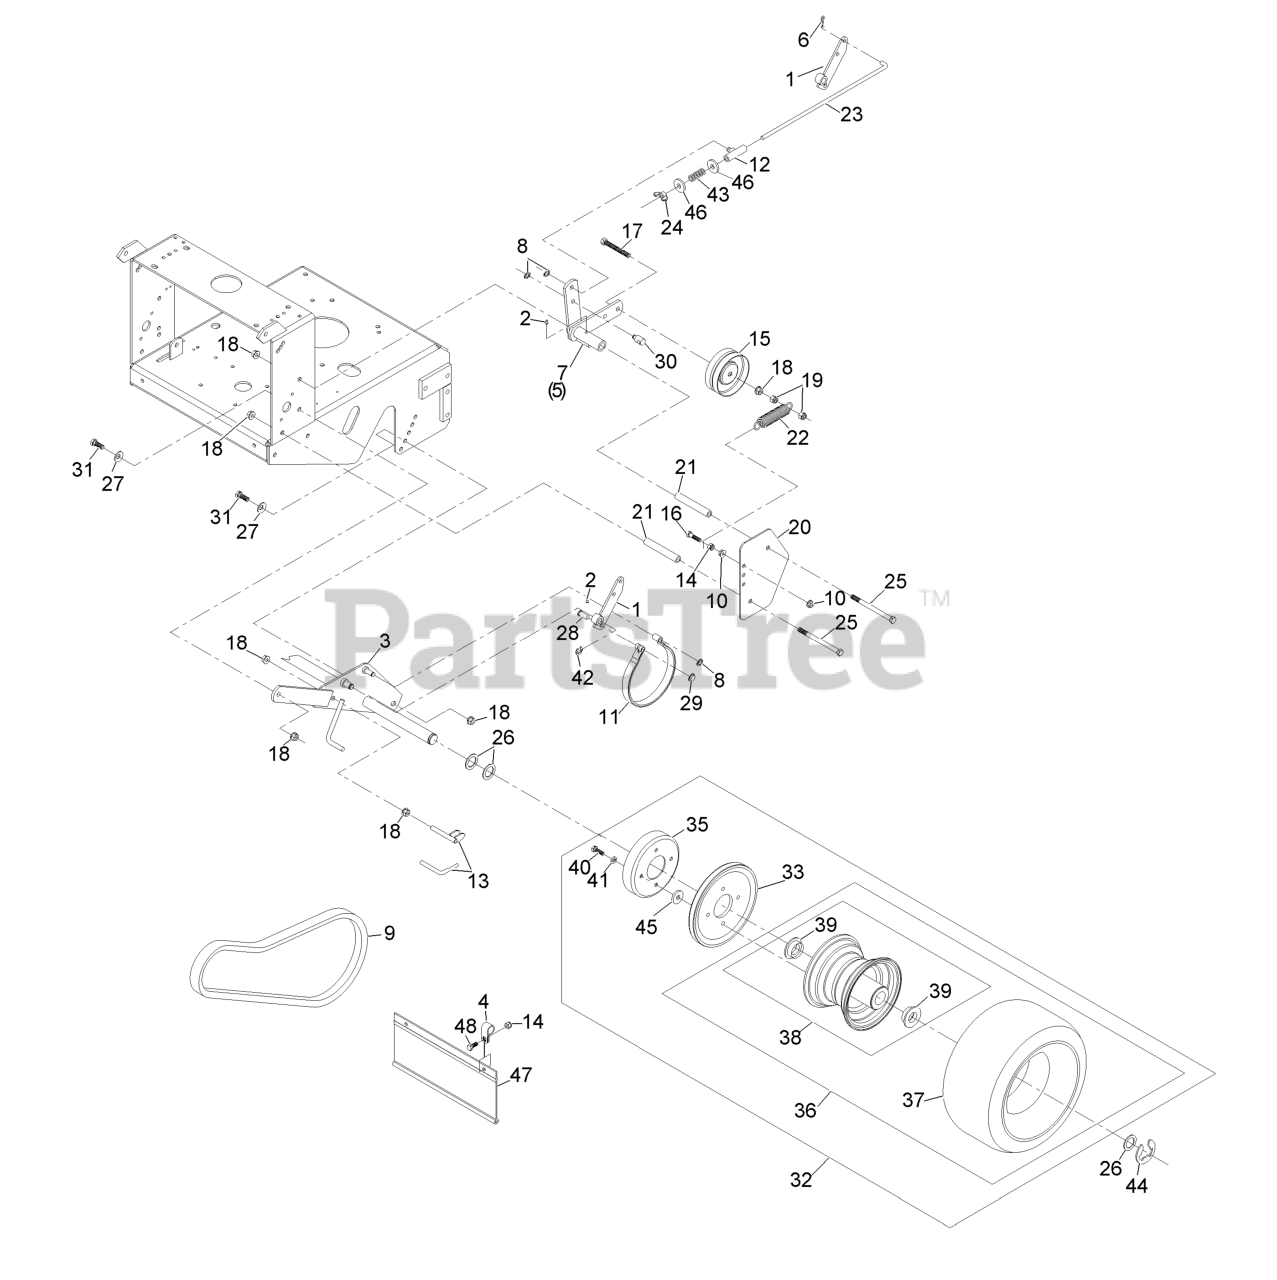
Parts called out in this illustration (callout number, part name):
1	ARM-BRAKE
2	FITTING-GREASE
4	CLAMP-R
6	PIN-COTTER
8	RING-RETAINING
9	BELT-WHEEL, DRIVE
11	BAND-BRAKE
12	SWIVEL-BRAKE
13	SCRAPER
14	NUT-LOCK, NI
15	IDLER-WHEEL, DRIVE
16	SCREW-HH
17	SCREW-HH
18	NUT-HHF, WHIZ
19	NUT-LOCK, NI
20	SHIELD-WHEEL, DRIVE
21	SPACER-SHIELD
22	SPRING-EXTENSION
23	LINKAGE-BRAKE
24	WINGNUT-NYLOCK
25	SCREW-HH
26	WASHER-SPACER
27	WASHER-BELLEVILLE
28	PIN-CLEVIS
29	RING-RETAIN,PUSH,EXT,FLAT
30	SWIVEL-LEVER, DRIVE
31	SCREW-HH
32	DRIVE WHEEL ASM
33	SHEAVE-WHEEL, DRIVE
35	DRUM-BRAKE
36	WHEEL AND TIRE ASM
38	WHEEL AND HUB ASM
39	BEARING-FLANGED
40	SCREW-HH
41	WASHER-LOCK
42	RING-RETAINING, EXTERNAL
43	SPRING-COMPRESSION
44	RING-SNAP
46	WASHER-PLAIN
47	SHIELD-TRAILING
48	SCREW-HH
